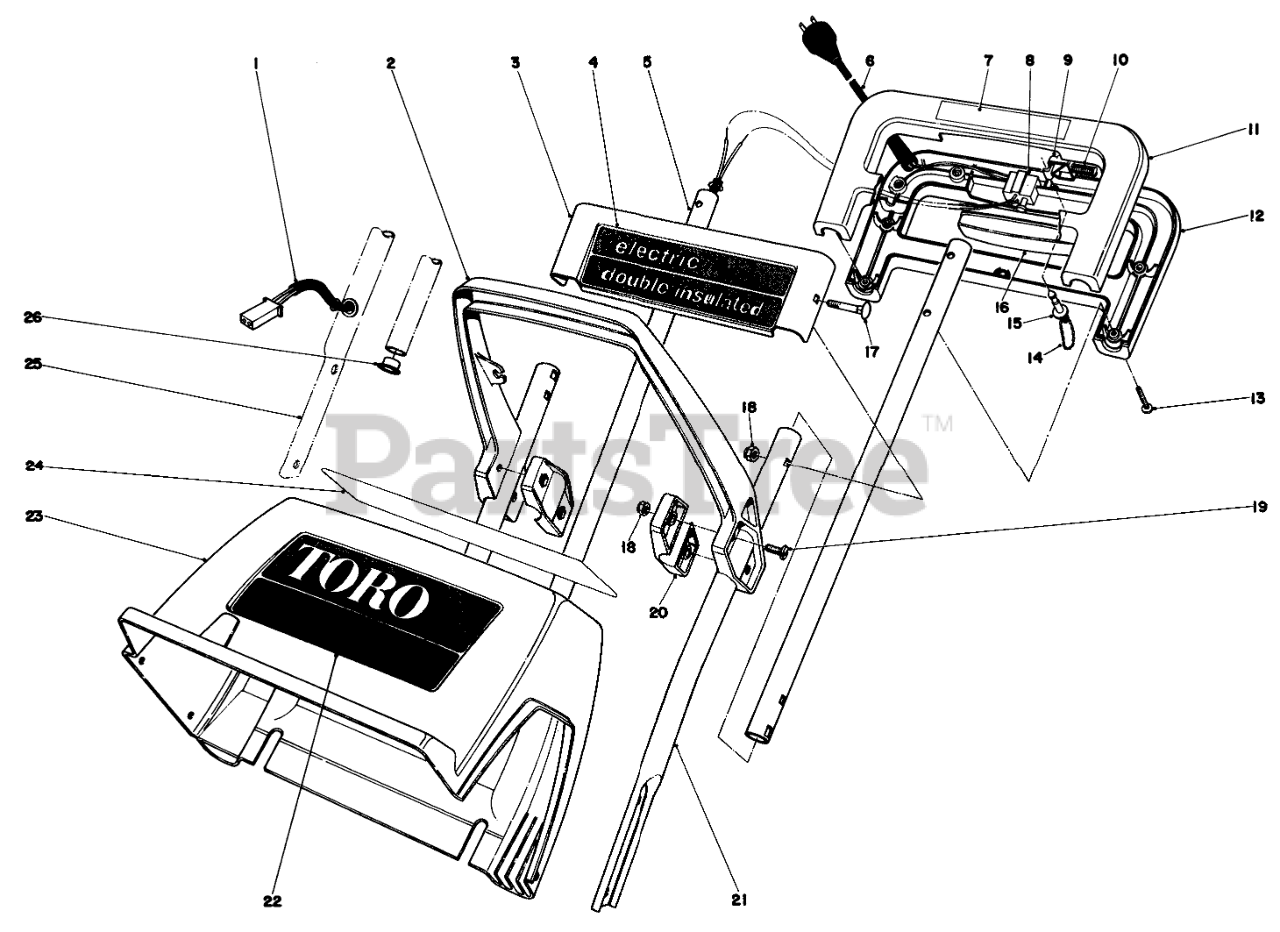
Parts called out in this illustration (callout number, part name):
1	Wire Harness
2	Middle Handle
3	Escutcheon Plate
4	Decal-Electric
5	Upper Tube
6	Cord Supply
7	Decal-Handle
8	SWITCH-STARTER
9	LOCKOUT, 1200
10	COMP SPRING
11	UPPER CONTRL HANDL HID
12	LOWR CONTRL HANDL HID
13	Screw
14	Key Chain
15	Key
16	SWITCH BAR, 1200 PC
17	Bolt-Carriage
18	NUT-LOCK, NI
20	Clamp-Middle Handle
21	Handle-Lower L.H.
22	Decal-Toro S-120
23	Shroud S-120
24	Decal-U.L
25	Handle Lower R.H.
26	Snap Bushing
